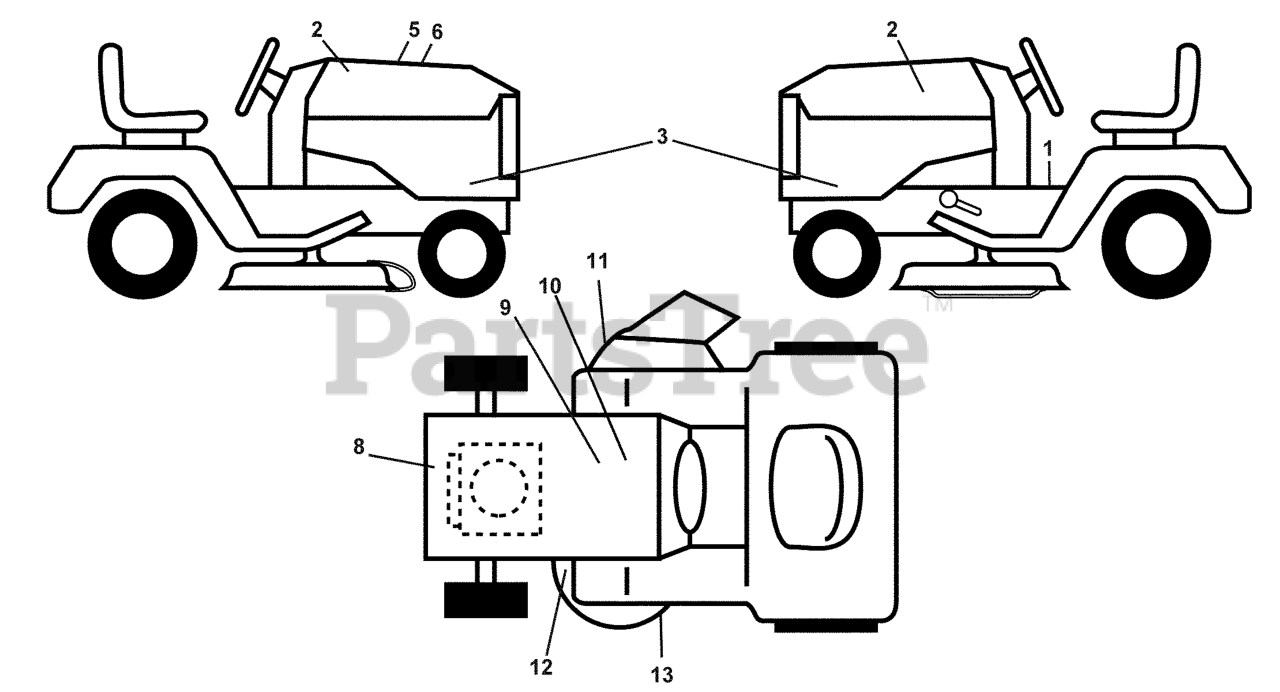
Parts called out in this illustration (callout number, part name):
1	DECAL.FENDER.WARNING.ENG
2	DECAL.HOOD.LOGO.ORANGE.HUSQVAR
3	DECAL, PANEL SIDE
5	DECAL.WARNING.CUST.RESP.E85.
8	DECAL, ENG. HP
9	DECAL BTRY SYMBOLS
10	DECAL.BATTERY
11	DECAL.WARN.KEEP.HAND.AWAY
12	DECAL CLUTCH/BRAKE
13	DECAL.MOWER.SCH.48/54
